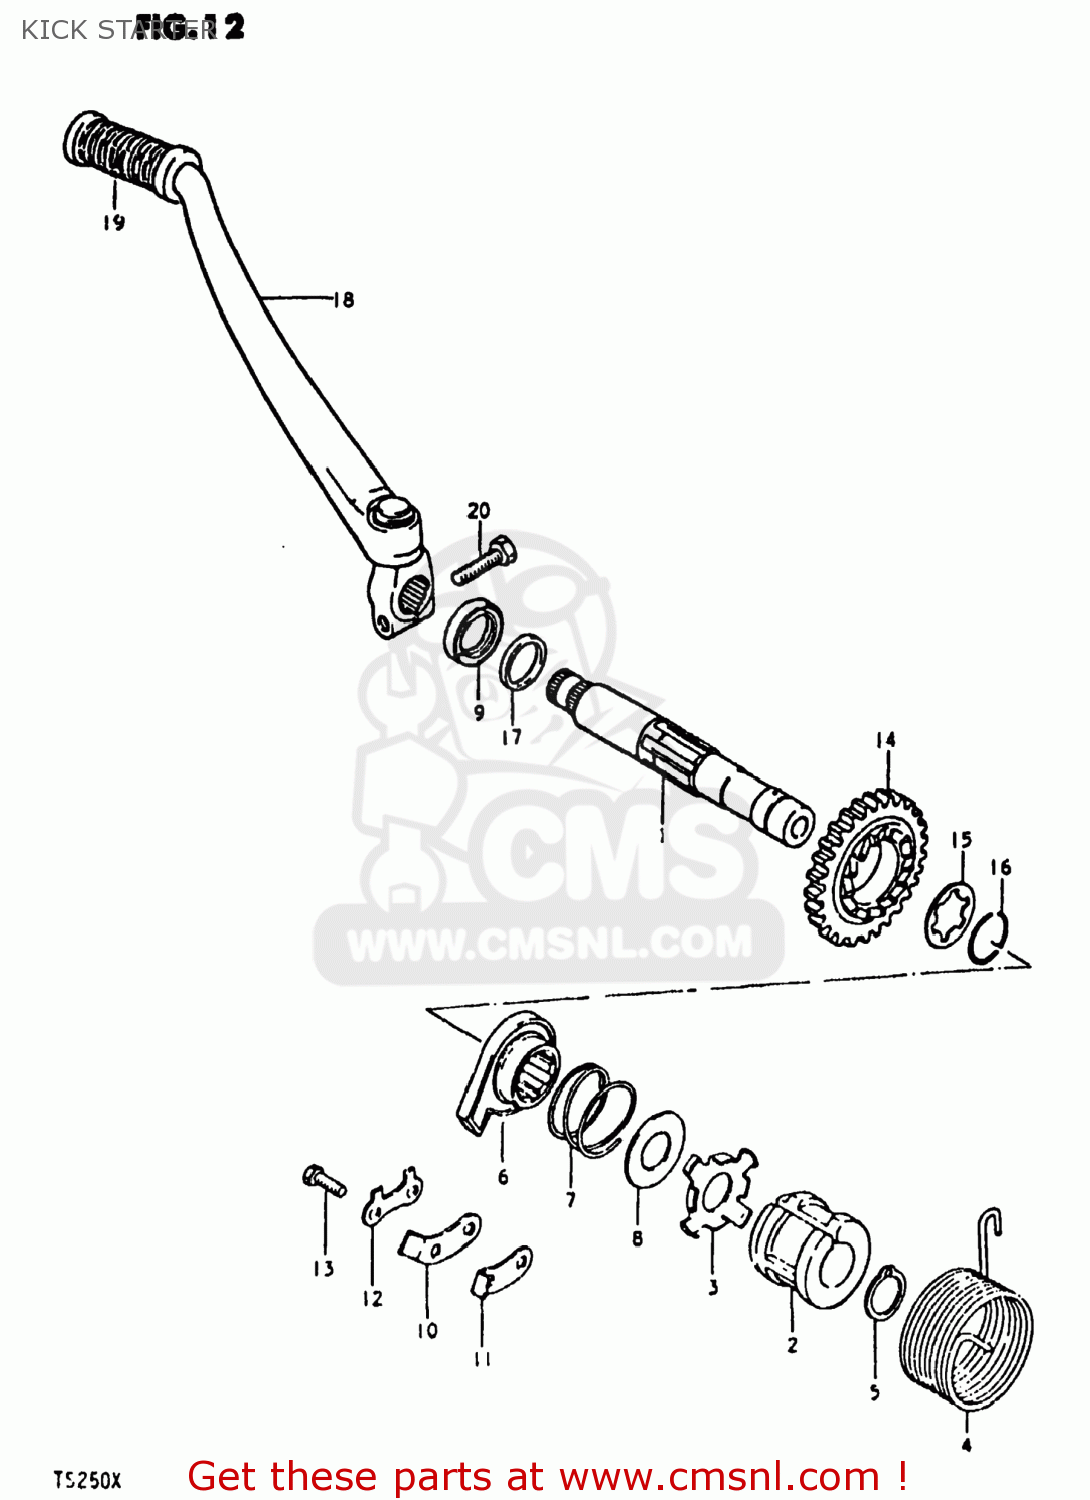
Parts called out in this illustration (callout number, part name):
1	SHAFT,KICK STARTER
2	GUIDE,KICK SHAFT SPRING
3	HOLDER,KICK SHAFT SPRING
4	SPRING
5	CIRCLIP
6	STARTER,KICK
7	SPRING
8	WASHER
9	SEAL,OIL(20X37X7)
10	GUIDE,KICK STARTER
11	STOPPER,KICK STARTER
12	WASHER
13	BOLT, UPPER
14	GEAR,KICK STARTER DRIVE
15	WASHER,LOCK
16	CIRCLIP
17	SPACER(20X28X4.5)
18	LEVER ASSEMBLY,KICK STARTER
19	RUBBER,KICK STARTER PEDAL
20	BOLT
